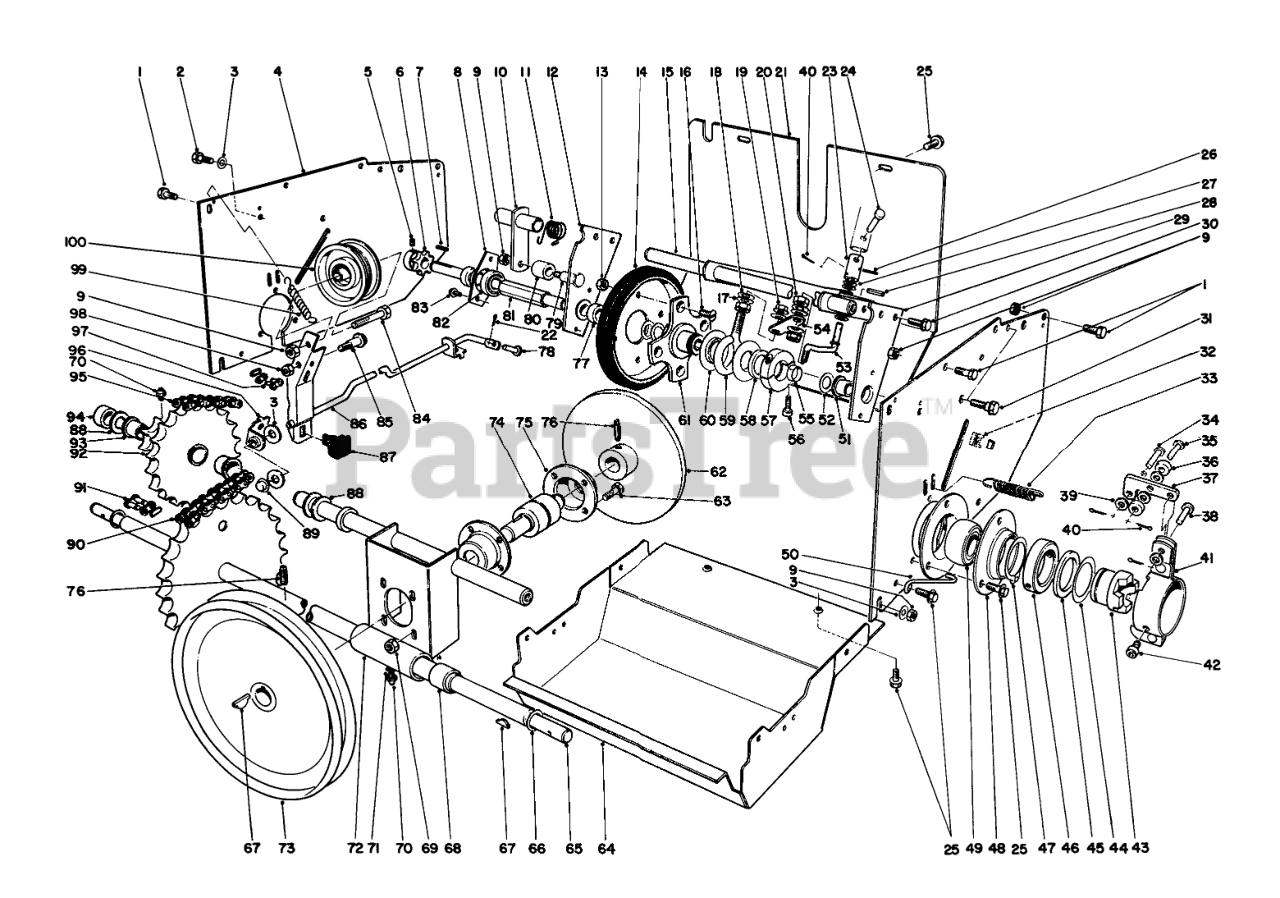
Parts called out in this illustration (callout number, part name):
1	SCREW-HH
2	SCREW-HWHTF
3	WASHER-FLAT
4	Side Plate Drive
5	SCREW-HSH
6	SPROCKET
8	BEARING CUP
9	NUT-LOCK, NI
10	CHAIN TENSION ARM WA
11	TORSION SPRING
12	HEX SHAFT MOUNT R
13	NUT-LOCK, NI
14	FRICTION WHEEL
15	Bracket Dead Shaft
16	5/16-18X5/8 FLT HD MS
17	WASHER-FLAT
18	WASHER-SPRING
19	NUT-LOCK, FLANGE
20	NUT-LOCK
21	REAR COVER R
22	PIN-COTTER
23	U JOINT TUBE
24	CLEVIS PIN
25	SCREW-HWH
26	PIN-SPRING
27	Clevis Pin
28	PIN-ROLL
29	Hex Shaft Mounting (Incl. Ref. #51)
30	SCREW-HWHTF
31	SHOULDER SCREW
32	RETAINER NUT
33	EXTENSION SPRING
34	PIN-CLEVIS
35	PIN-CLEVIS
36	CLUTCH ROLLER
37	CLUTCH CAM ARM
38	PIN-CLEVIS
39	WASHER-FLAT
40	PIN-COTTER
41	CLUTCH MT BRKT ASM
42	SCREW-HSH
43	WHEEL CLUTCH
44	THRUST WASHER
45	THRUST BEARING
46	CLUTCH MOUNT COLLAR
47	RING-RETAINING, EXTERNAL
48	BEARING FLANGE
49	BEARING
50	CLUTCH RETAINER
51	BUSHING
52	WASHER-FLAT
53	CONNECTION ROD
54	SHIFT ROD PIVOT
55	SPLIT SPACER
56	SCREW-HSH
57	ColIar
58	WASHER-THRUST
59	SLIDER RING COLLAR
60	SLIDER RING
61	TRACTION DISC HUB
62	FRICTION PLATE O
63	SCREW-HH
64	LOWER SHIELD R
65	AXLE SHAFT WA
66	WASHER
67	KEY-WOODRUFF
68	Bearing
69	NUT-KEPS
70	FITTING-GREASE
71	WASHER-LOCK
72	Bulkhead (Incl. Ref. #68)
73	Pulley
74	BEARING-FRICTION PLATE
75	HOUSING BEARING
76	SCREW-SET, SQH
77	SPACER
78	PIN-CLEVIS
79	SHOULDER BOLT
80	CHAIN TENSION ROLLER
81	FRICTION WHEEL SHAFT
82	BEARING
83	SCREW
84	SCREW-HH
85	BOLT-SHOULDER
86	Auger Brake Assembly (Incl. Ref. #87)
87	Brake Pad
88	WASHER-THRUST
89	PUSH NUT
90	Lower Chain (Incl. Ref. #91)
91	LINK-CHAIN
92	Sprocket (Incl. Ref. #70 & 93)
93	3/4ID X 3/4LG BSHG
94	SPACER-IDLER
95	Upper Chain (Incl. Ref. #97)
96	Bracket-Clutch
97	LINK-CONNECTING
98	NUT-LOCK, CONE
99	SPRING
100	PULLEY-IDLER
